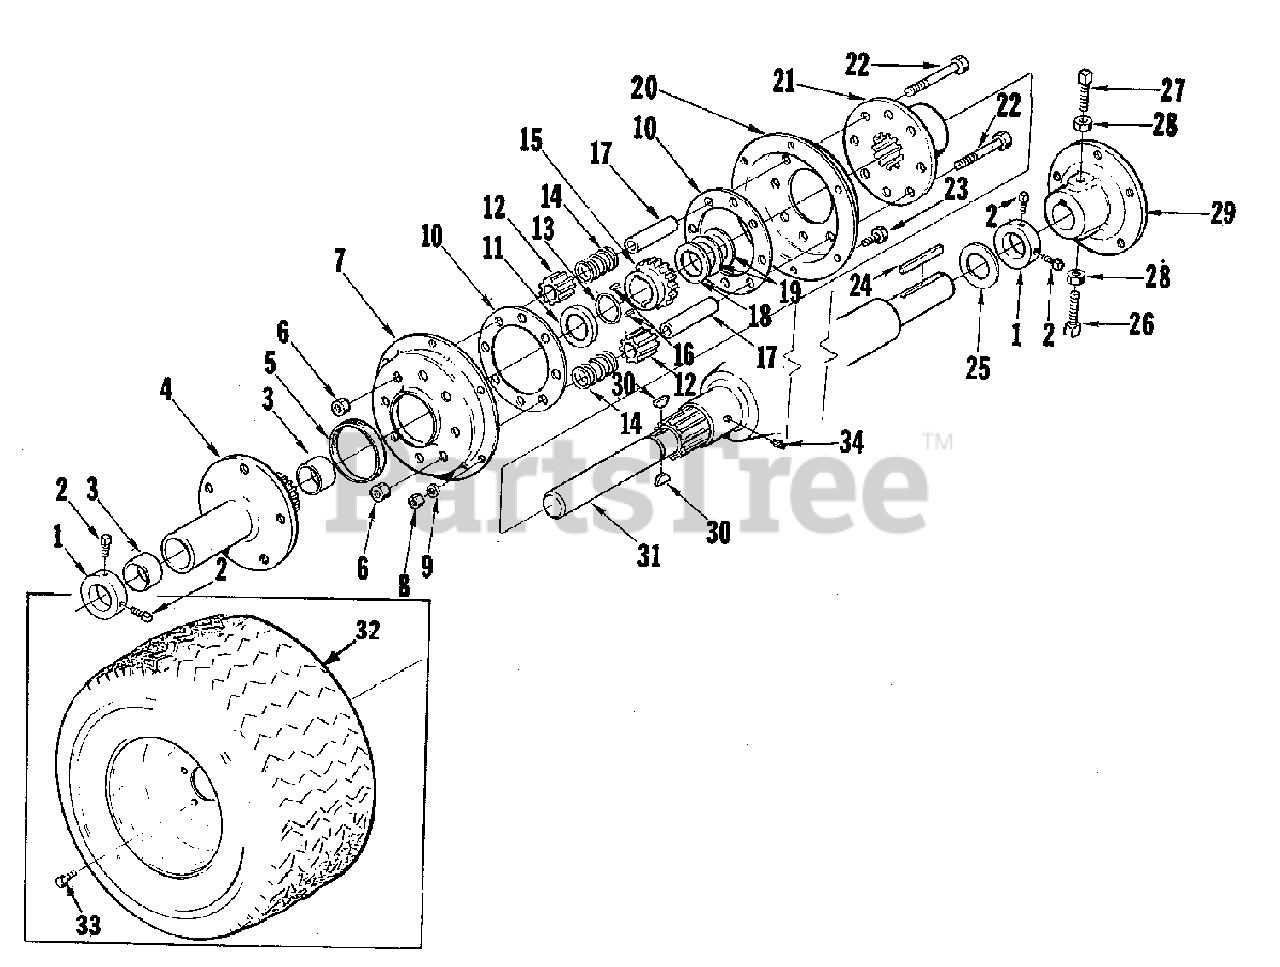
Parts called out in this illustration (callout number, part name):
1	COLLAR, Axle
2	SETSCREW, Square, 5/16-18 x 3/8
4	HUB ASSEMBLY, Wheel (R.H.)
5	SEAL, Differential
6	NUT, Hex Lock, 3/8-16
7	COVER, Differential
8	NUT, Hex Fin, 1/4-20
9	LOCKWASHER, 1/4
10	RING, Spacer
11	WASHER, Axle
12	PINION, Differential
13	RING, Retaining
15	GEAR, Differential
17	SPINDLE, Pinion Differential
18	WASHER, Axle
19	WASHER, Axle
20	COVER, Differential
21	CARRIER, Differential
22	SCREW, Hex Cap, 3/8-16 x 2-1/2
23	SCREW, Hex Head Cap, 1/4-20 x 5/8
26	SCREW, 3/8-16 x 1-1/2
28	NUT, Jam, Hex, 3/8-16
29	HUB, Wheel (L.H.)
32	WHEEL & TIRE, Rear 23 x 8-1/2-12 (T-10)
32	WHEEL & TIRE, Rear 23 x 10-1/2
34	FITTING, Grease
